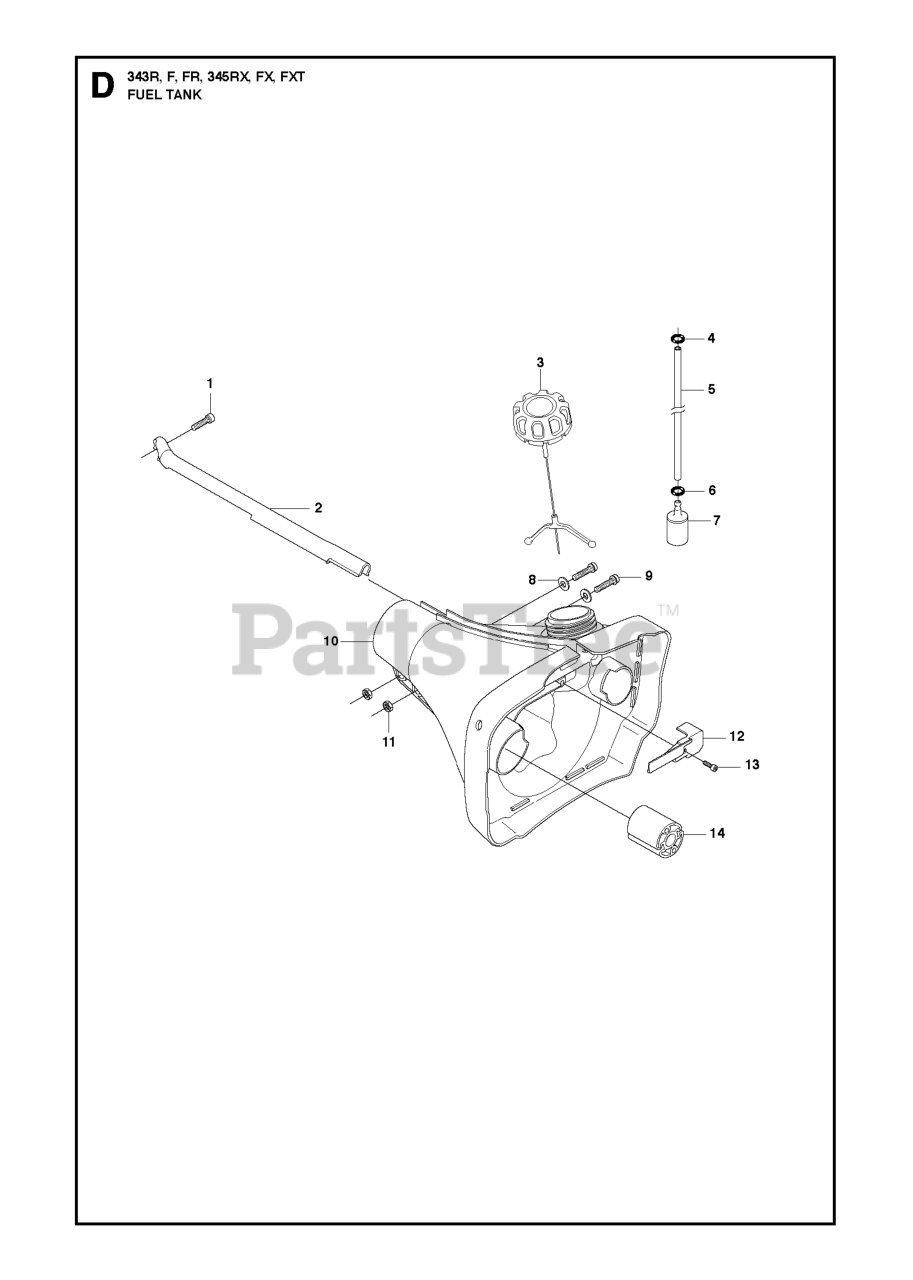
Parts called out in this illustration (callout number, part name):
2	PROTECTOR
3	%WINTER TANK CAP
5	FUEL HOSE
7	RP FUEL FILTER
8	WASHER 5.3X12
10	TANK UNIT
13	SCREW
14	ANTIVIBRATION ELEMENT
